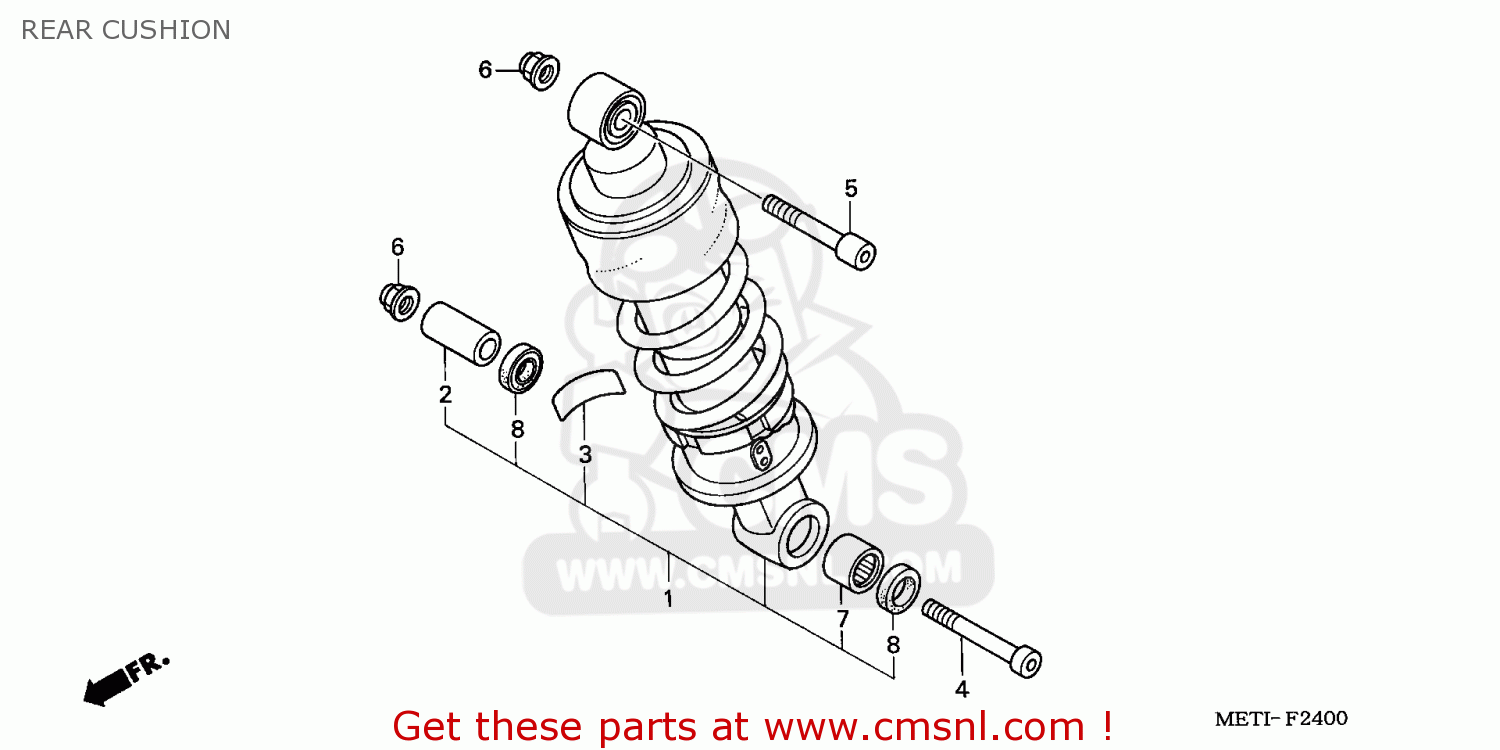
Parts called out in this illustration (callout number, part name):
1	CUSHION ASSY,REAR
2	COLLAR,CUSH CONN
3	LABEL,RR DAMPER
4	BOLT,SOC 10X57
5	BOLT,SOCKET 10X48
6	NUT,U,FLANGE,10MM
7	BEARING,NEEDLE (K
8	DUST SEAL,17X24X5
